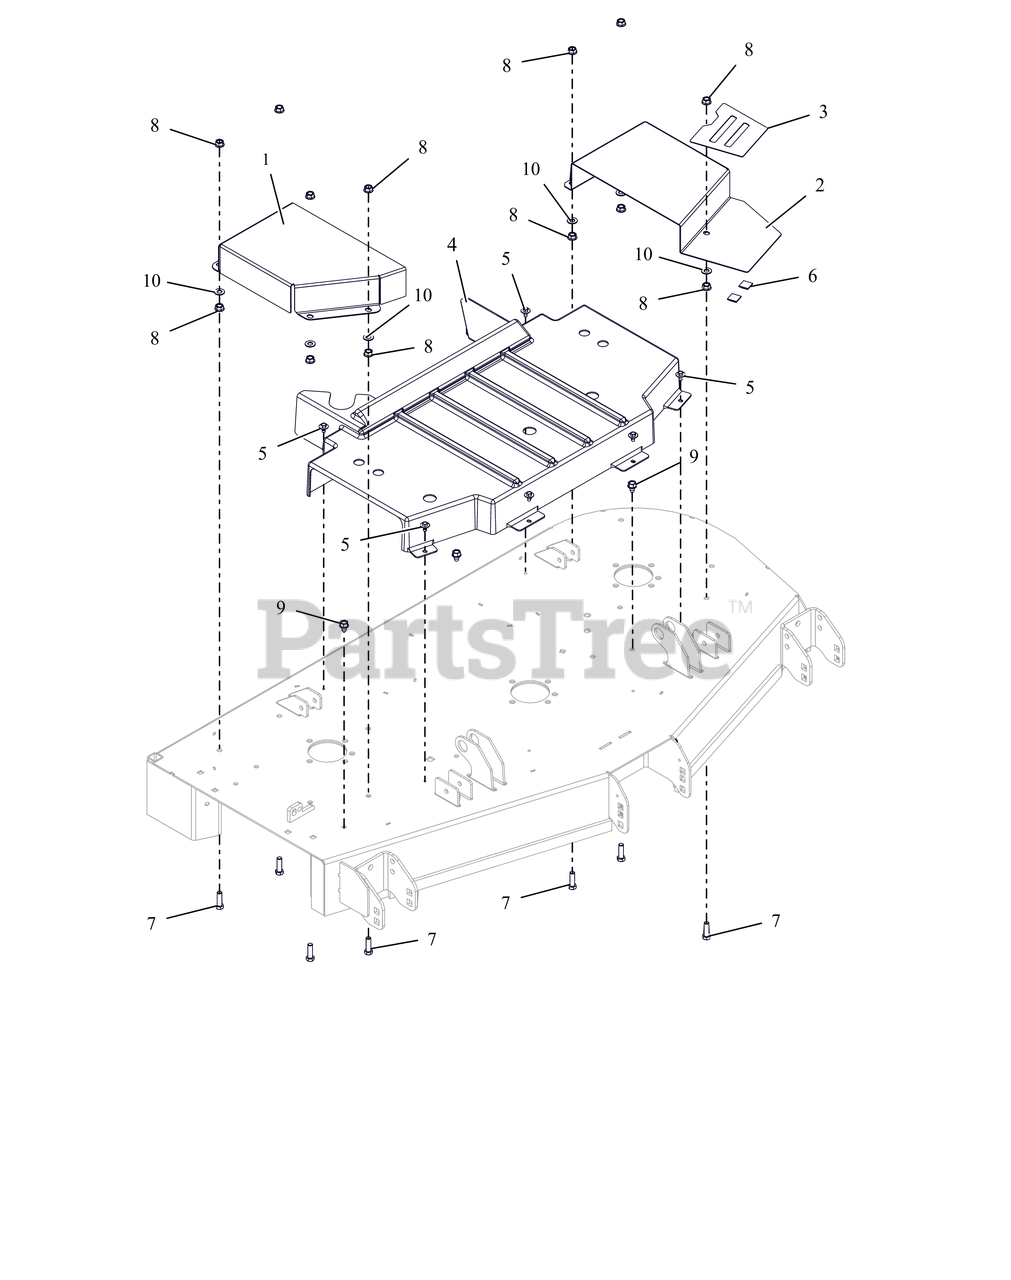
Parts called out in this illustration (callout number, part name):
1	GUARD,BELT 52" RIGHT CE
2	GUARD,BELT 52" LEFT CE
3	GRIP TAPE 52-60 BELT COVER
4	GUARD,CENTER,DECK SPINDLE CE
5	SCR-TAP .25-20X.50 LGHWH TR YZ
7	@BLT-HEX .38-16X1.25 GR5 YWZC
8	@NUT-SPNLK-FLG .375-16 YWZC
9	@SCR-TAP .38-16X.50 HWH TR YWZ
10	@WSHR-FL-STL.406X.812X.065 YWZ
